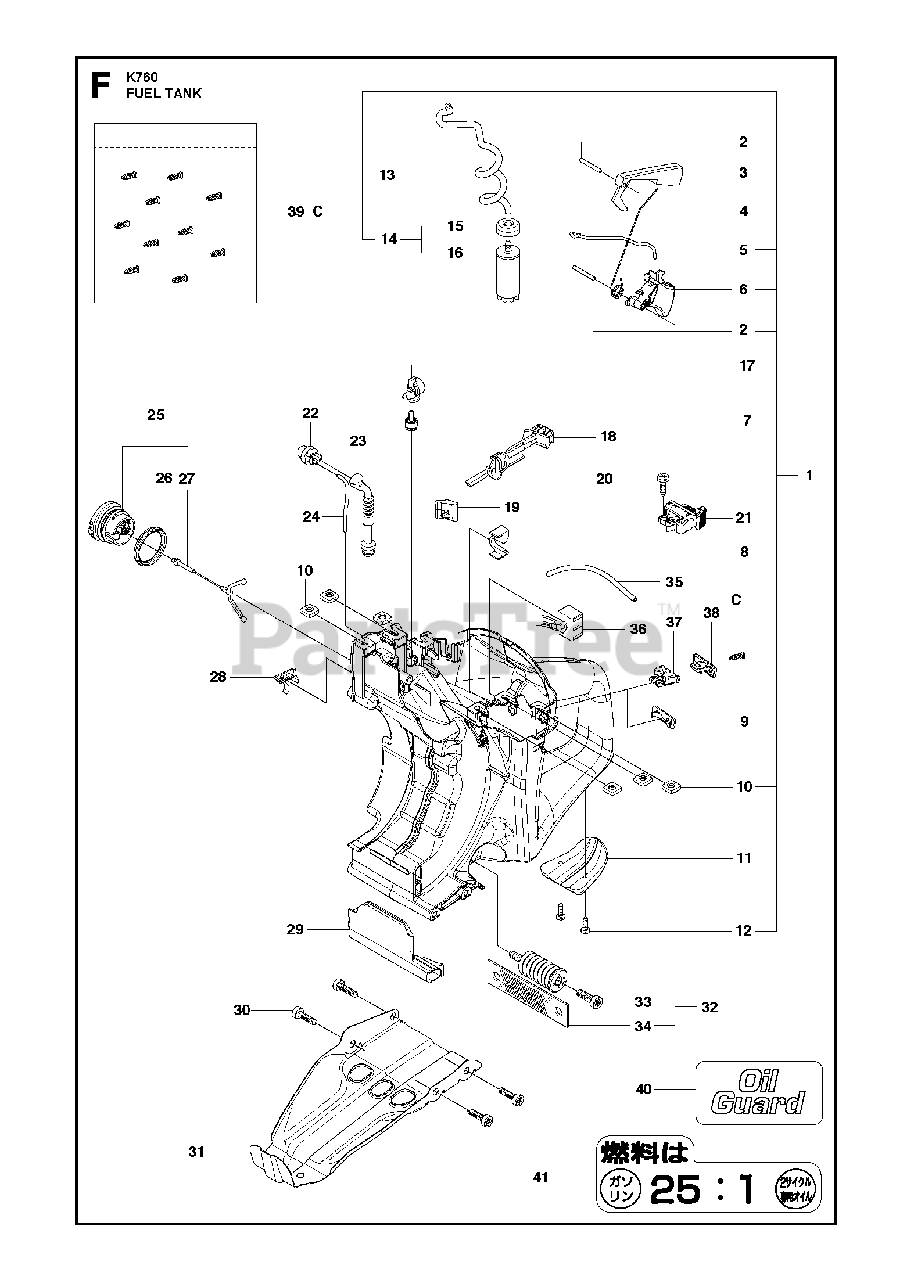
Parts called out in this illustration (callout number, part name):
1	FUEL TANK ASSYIncl. 2 - 14, 17
2	PARALLEL PIN
3	THROTTLE LOCKOUT
3	THROTTLE LOCKOUTOil Guard
4	SPRING
5	THROTTLE ROD
6	THROTTLE CONTROL
6	THROTTLE CONTROLOil Guard
7	TANK VENT ASSY
11	GROUND SUPPORT
12	SCREW CRCSFT
13	FUEL HOSEOil Guard
14	FUEL FILTERIncl. 15 - 16
17	TANK VENT VALVE ASSY
18	CHOKE CONTROL
20	SCREW CCRPANT
21	STOP SWITCH
23	FUEL HOSEPurge
24	FUEL HOSEPurge
25	TANK CAP ASSYIncl. 26 - 27
30	SCREW ITXSCT
32	ANTIVIBRATION ELEMENTIncl. 33 - 34
33	SCREW ITXSCM
36	ELECTRONIC BOXOil Guard
37	HOUSINGOil Guard
38	SWITCHOil Guard
39	KITOil Guard, Incl. 10 pins
40	LABELOil Guard
41	LABELJapan only
